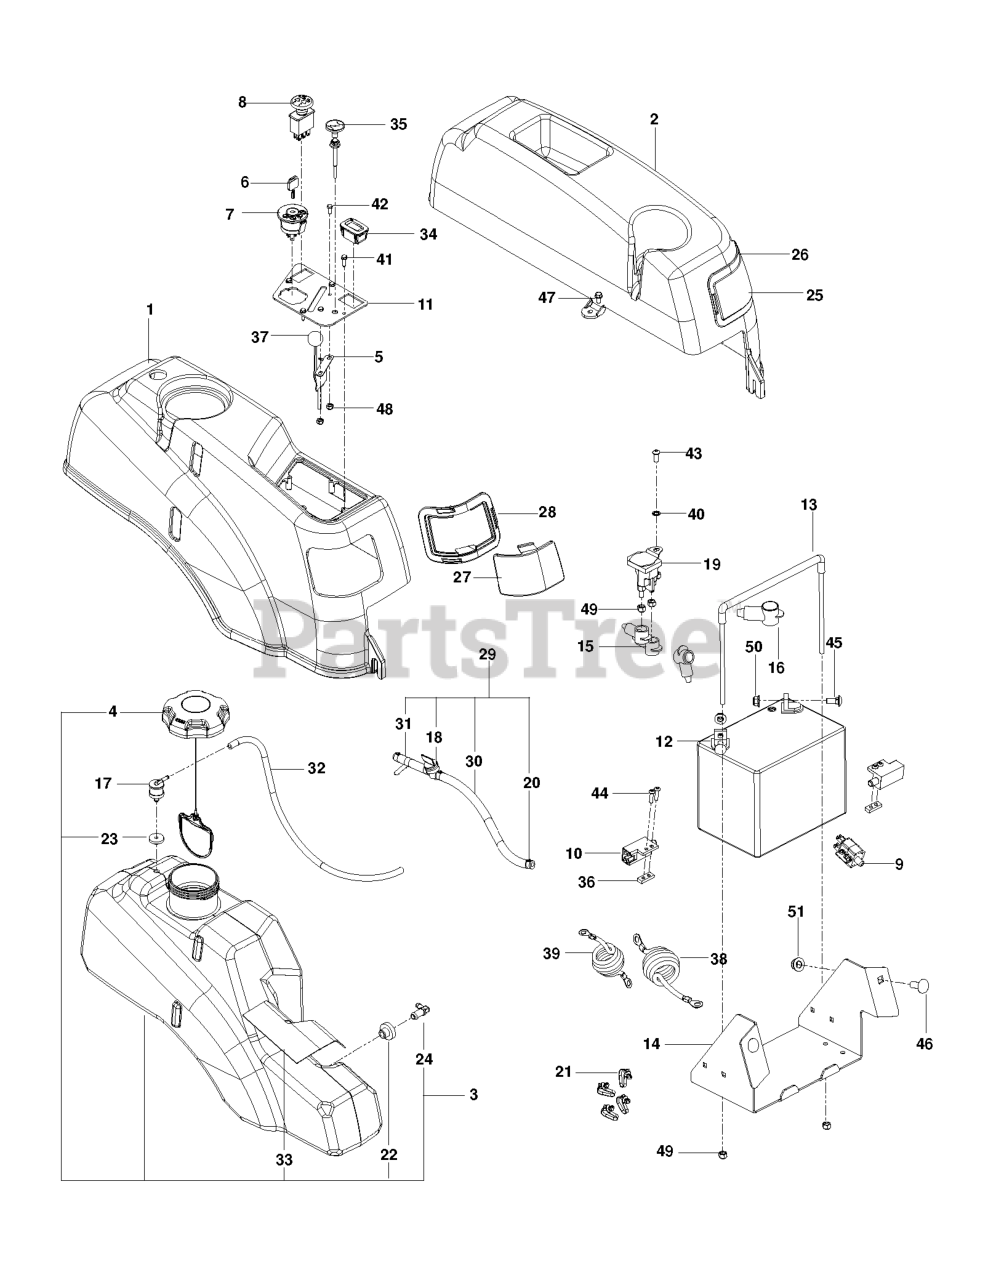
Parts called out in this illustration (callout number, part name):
1	FENDER RT, GRAY
2	FENDER, LT
3	TANK.FUEL.RT.EPA
4	CAP, FUEL
5	THROTTLE CONTROL W/BALL KNOB
6	KEY
7	RP IGNITION SWITCH
8	RP.SWITCH, BLADE
9	SWITCH, BRAKE 3P
10	SWITCH, INTERLOCK
11	CONSOLE.PLATE.BLACK
12	BATTERY, 12 V 330 AMP
13	BATTERY TIE DOWN ASSEMBLY
14	BOX, BATTERY, BLACK
15	TERMINAL COVER-SM
17	VALVE.FUEL.CHECK
18	FUEL VALVE
19	SOLENOID.W/BRASS.PLUNGER
19	SOLENOID
20	HOSE CLAMP
21	TIE WRAP, 8-3/8", W/CLIP
22	RUBBER GROMMET
23	GROMMET, CHECK VALVE
24	STEM, FUEL TANK
25	LENS, COLORED LEFT
26	LEFT HEADLIGHT RIM GREY
27	LENS, COLORED RIGHT
28	RT HEADLIGHT RIM GREY
29	FUEL LINE ASSY
30	GAS LINE 10"
31	FUEL LINE 3"
32	HOSE, FUEL, 3/16" X 17-1/4"
33	SHIELD, HEAT
34	RP.GUAGE.SRVCMNDR.HRMTR.
35	CHOKE CONTROL, COMPLETE
36	TAPPED PLATE
37	KNOB.ROUND.BALL.BLACK
38	CABLE POSITIVE, LONG
39	BATTERY CABLE, NEGATIVE
40	WASHER 1/4 INT TOOTH
41	SCR #10-12X3/4 HEX WAS HD ZD
42	HCS #10-24 X 1/2
43	SCR 1/4-20 X 5/8 BTN SKT HD ZD
44	SCR #10-24 X .75 SKT HD BLK
45	RP BOLT 5/16-18 X3/4 ZN/YEL GR
46	BOLT D
47	SCREW
48	NUT 10-24 NYLOC
49	LOCKNUT.NYLOC.1/4-20
50	5/16-18 NYLOC FLANGE NUT
51	NUT 3/8-16 HEX FLG NYLOC ZD
